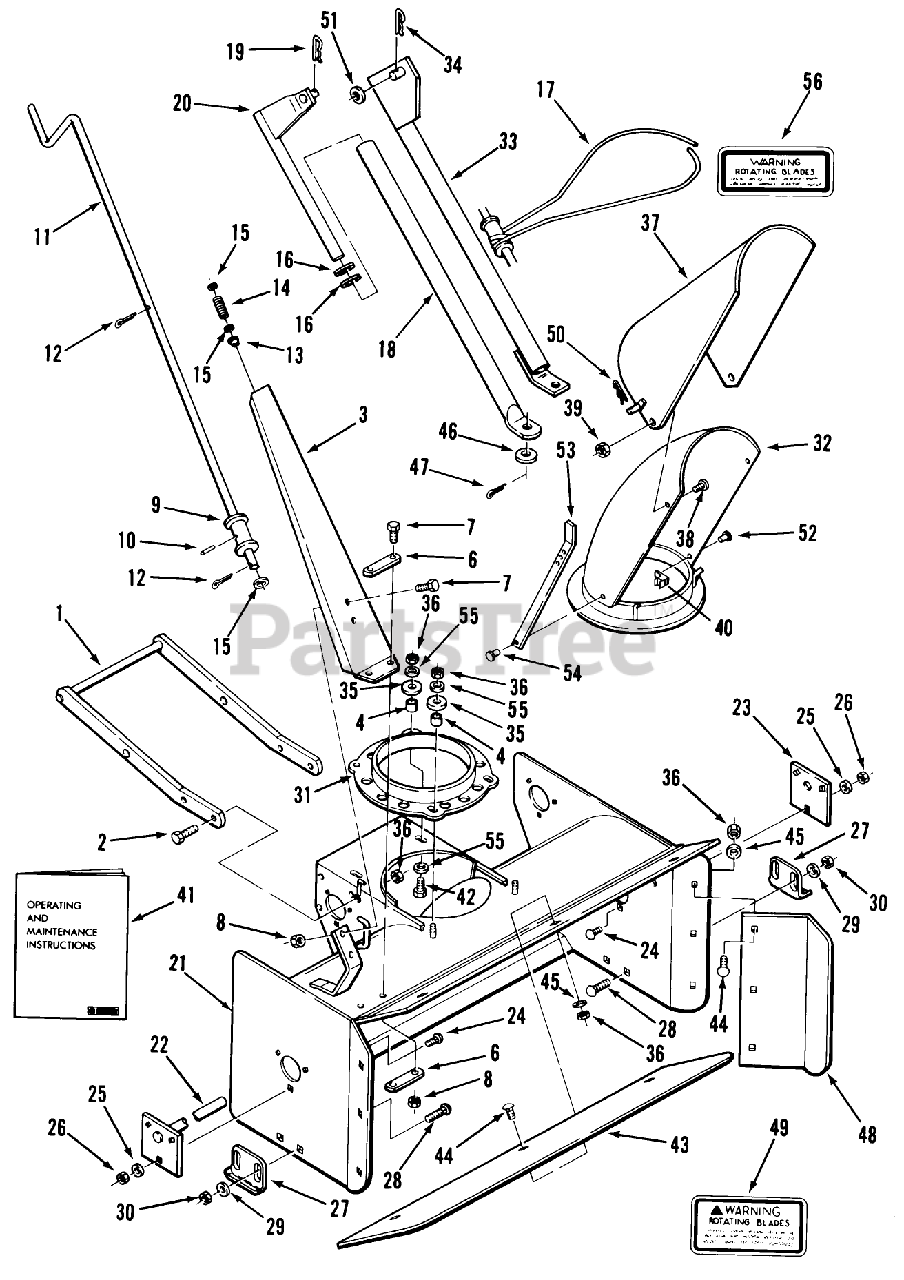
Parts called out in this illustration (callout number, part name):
9	ASSY TUBE CRANK *R
10	ROLL PIN 1/4 X 1-1/4
13	NYLINER BUSHING
14	SPRING-COMPRESSION
17	CABLE
18	ASSY LIFT TUBE *R
19	Hairpin
21	Wrapper Assembly
24	CARRIAGE BOLT -4
33	ASSY LIFT TUBE
34	Hairpin Cotter
35	WASHER
40	CLAMP
41	INST SHEET
50	Hairpin
52	RIVET-4
54	RIVET
56	DECAL-WARNING
